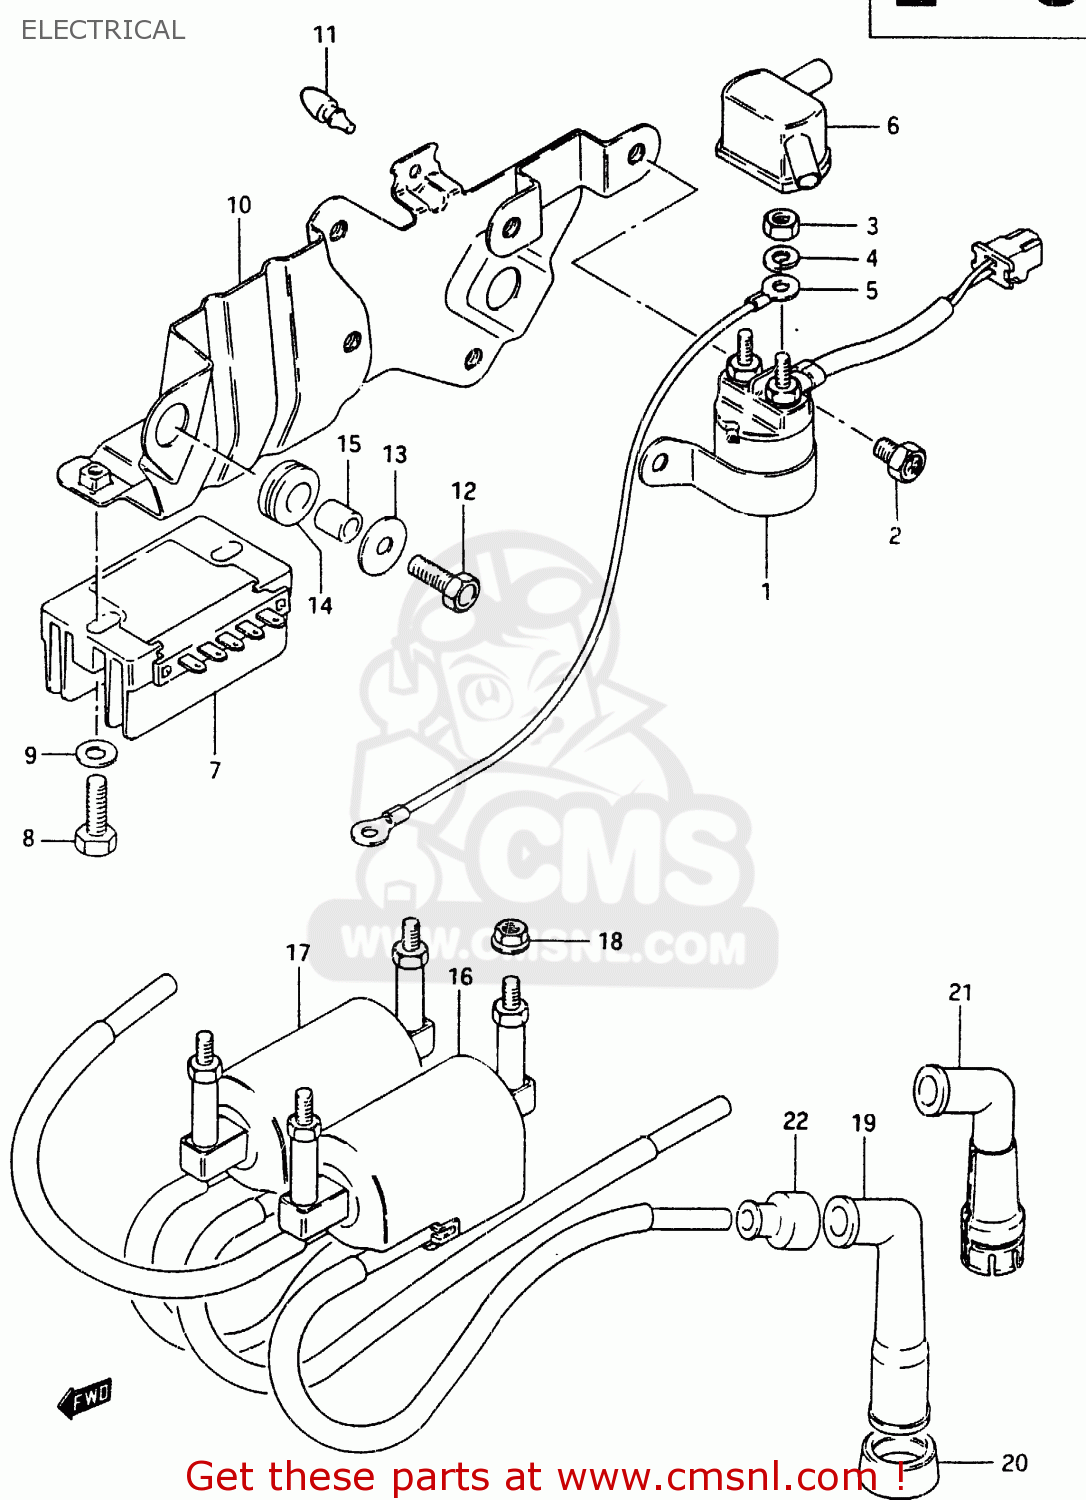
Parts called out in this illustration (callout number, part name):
1	RELAY ASSEMBLY,STARTING MOTOR
2	SCREW(6X10)
3	NUT
4	WASHER,LOCK
5	WIRE,STARTER MOTOR LEAD
6	CAP,STARTER RELAY TERMINAL
7	RECTIFIER ASSEMBLY
8	BOLT(6X20)
9	WASHER
10	PLATE,ELECTRIC PARTS H
11	CUSHION
12	BOLT
13	WASHER (6.5X20X1.2)
14	CUSHION
15	SPACER(6.1X9X7.5)
16	COIL ASSEMBLY,IGNITION
17	COIL ASSEMBLY,IGNITION NO
18	NUT
19	CAP,SPARK PLUG
20	SEAL,SPARK PLUG CAP
21	CAP, SPARK PLUG
22	SEAL,SPARK PLU
